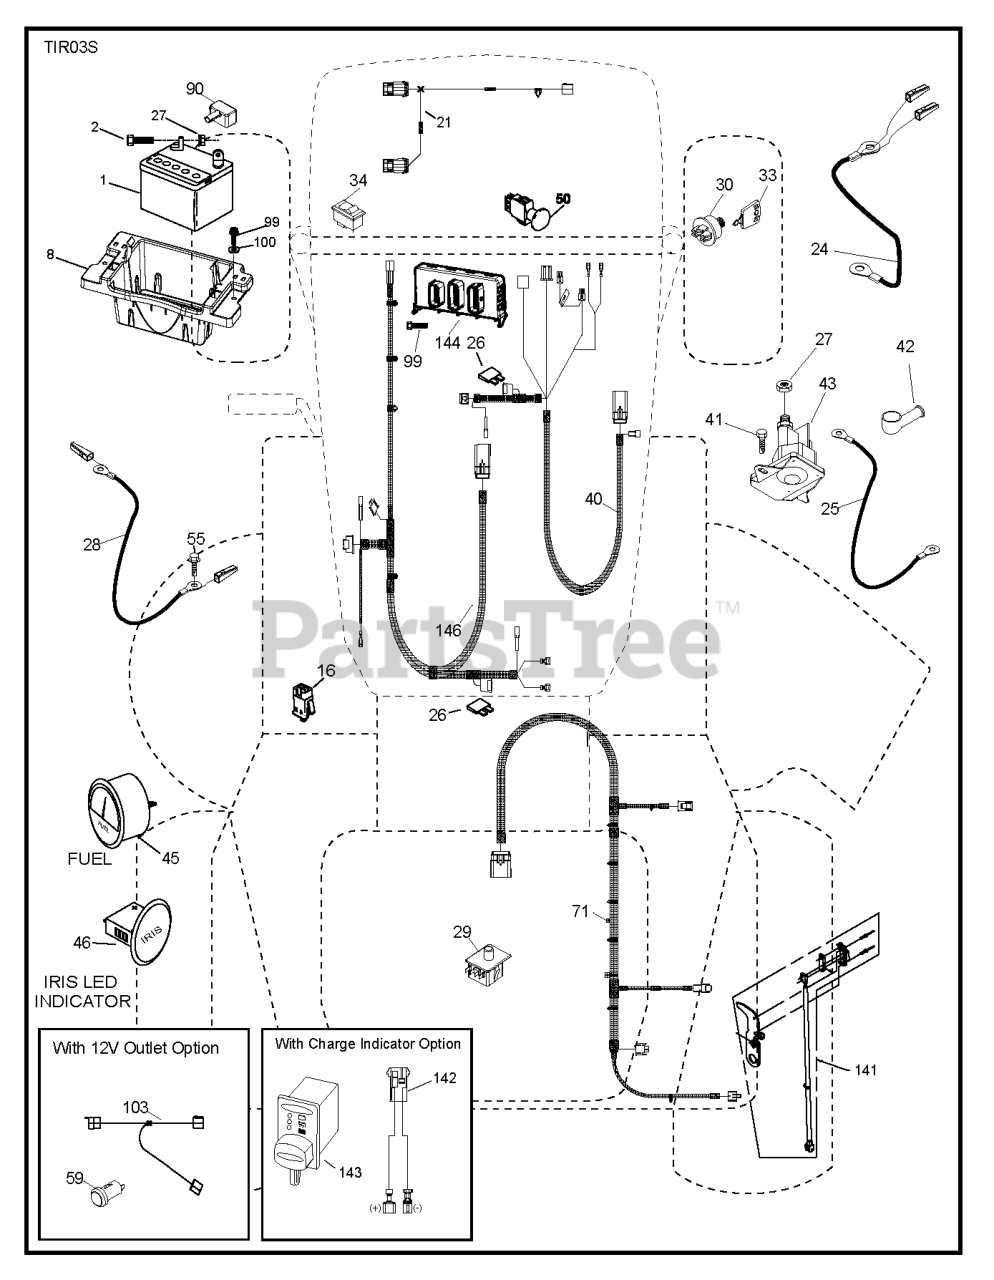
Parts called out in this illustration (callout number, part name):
1	Battery 12 Volt 25 Amp
2	BOLT.HEX.1/4.X.3/4.DICHROMATE
8	TRAY.ASM.BATTERY.FRT.TEX.CARB
16	SWITCH INTERLOOK PUSH-IN
21	HARNESS LIGHT ASSY TRACTOR,
24	PRIMARY CABLE POSITIVE, TWO HA
25	CABLE.STARTER.8GA.17.5
26	FUSE 20AMP
27	NUT
28	GROUND CABLE TWO HARNESS TAPS,
29	SWITCH SEAT, 4 PIN NC/NO
30	SWITCH.IGN.DELTA.W.LGH.ROS
33	KEY.CHAIN.BLISTER.PACK.GEN.USA
40	WIRING ASSY DASH, IRIS, 300, T
41	SCREW
42	TERMINAL COVER
43	SOLENOID.STARTER.BRASS.PLUNGER
45	GAUGE.FUEL.LEVEL. ROUND.2"
46	GAUGE.INDCTR.RND.2"FARIA.6ICNS
50	SWITCH.PTO.8TERMINAL.STD.BLK
55	SCREW 5/16"
59	OUTLET.12-VOLT
71	WIRING ASSY CHASSIS, IRIS, 300
90	COVER.TERMINAL.BATTERY
99	SCREW HEXWSHR 1/4-20X3/4
141	KIT.G700/G730.ROS 71750
144	CONTROL.UNIT.RIDE.ON.IRIS.BASE
146	WIRING ASSY ENGINE, IRIS, 300,
